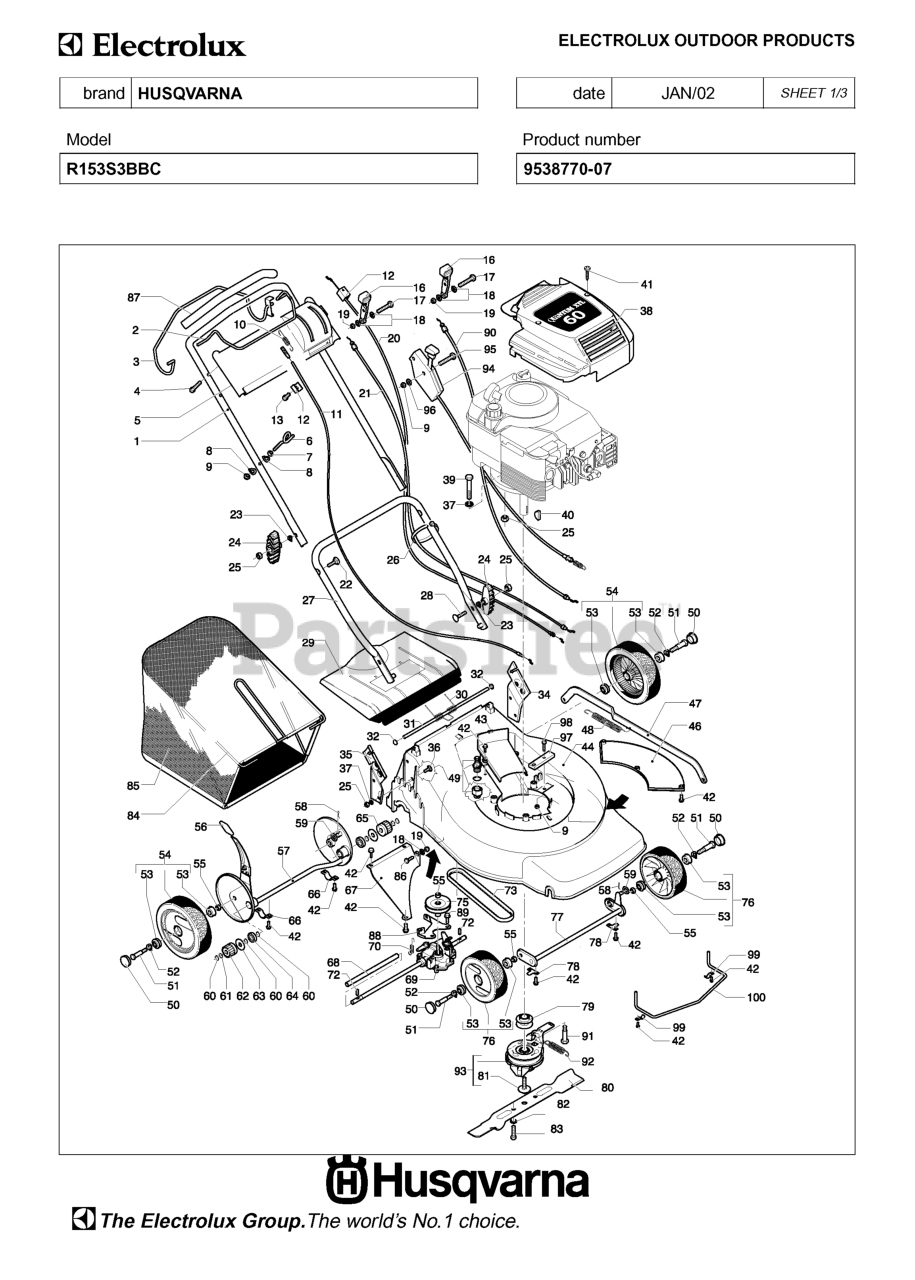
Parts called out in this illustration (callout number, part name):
28	Screws
42	Screws
58	Pins
60	Washers
